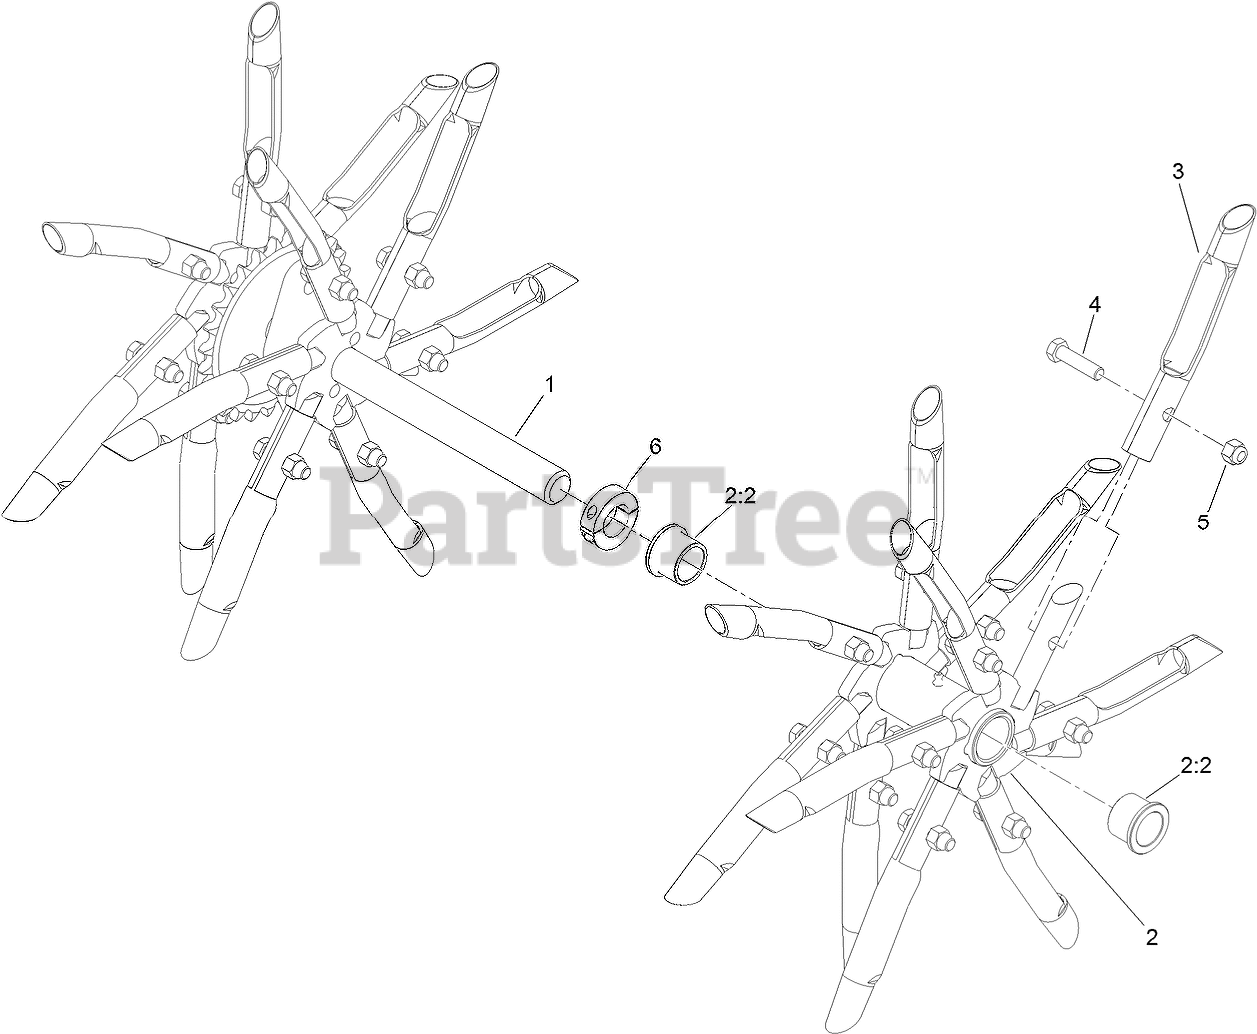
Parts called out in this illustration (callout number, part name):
1	TINE SHAFT-RH
2	ASM-FLOAT TINE SHAFT
2:2	BUSHING-FLANGE
3	TINE-CORING (3/4 INCH)
4	SCREW-HH
5	NUT-LOCK, NI
6	COLLAR-LOCKING
